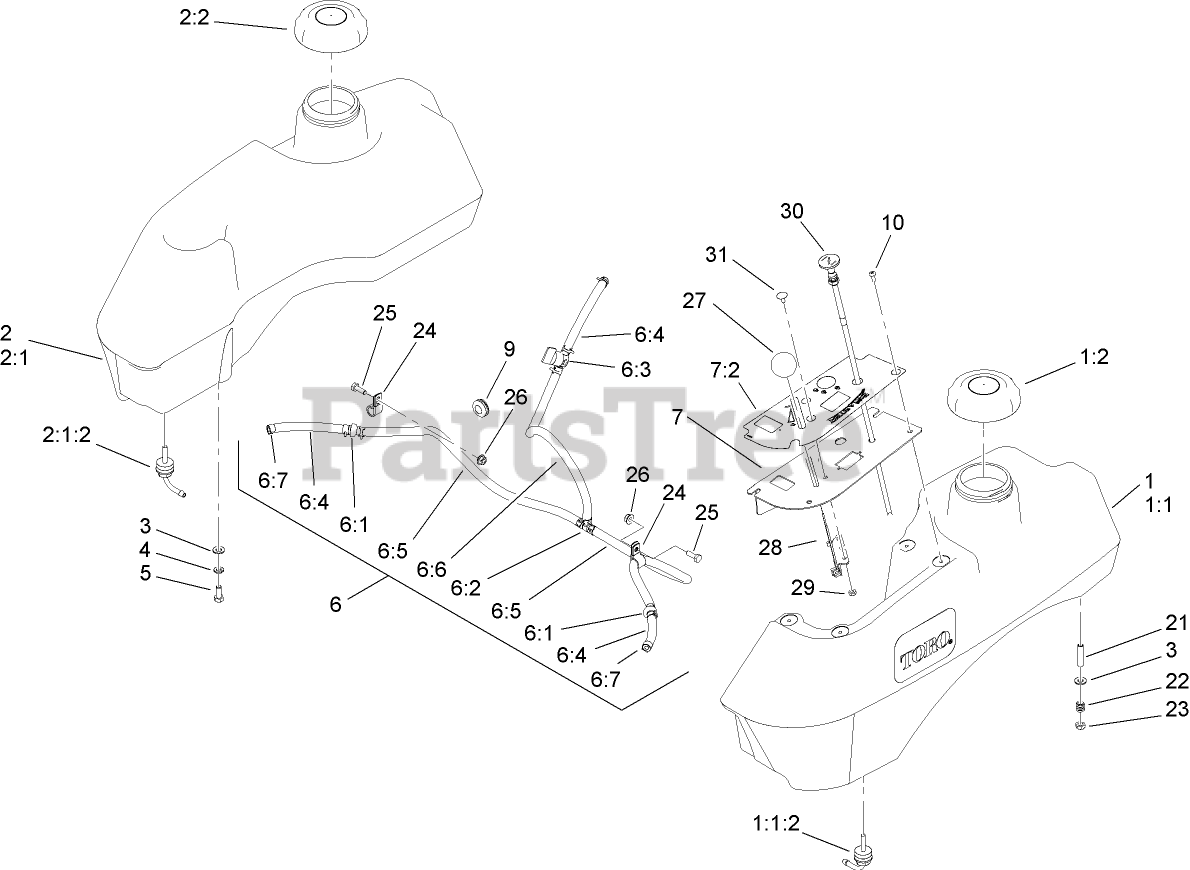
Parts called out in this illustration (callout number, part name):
1	LH FUEL TANK SERVICE KIT
1:1	LH FUEL TANK ASM
1:1:2	FITTING-FUEL, BULKHEAD
1:2	CAP-FUEL, GAS
2	RH FUEL TANK SERVICE KIT
2:1	RH FUEL TANK ASM
2:1:2	FITTING-FUEL, BULKHEAD
2:2	CAP-FUEL, GAS
3	WASHER-PLAIN
4	WASHER-LOCK
5	SCREW-HH
6	FUEL LINE ASM
6:1	VALVE-CHECK, FUEL
6:2	FITTING-TEE, BARBED
6:3	VALVE-FUEL
6:4	HOSE-FUEL
6:5	HOSE-FUEL
6:6	HOSE-FUEL
7	CONTROL PANEL ASM
7:2	DECAL-PANEL, CONTROL
9	GROMMET
10	SCREW-PPH
22	SPRING-TANK, FUEL
23	NUT-LOCK, NI
24	CLIP-LOOM
25	SCREW-HH
26	NUT-HF
27	KNOB-BALL
28	THROTTLE CABLE ASM
29	NUT-LOCK, NI
30	Control-Choke, Push / Pull
31	BOLT-CARR
